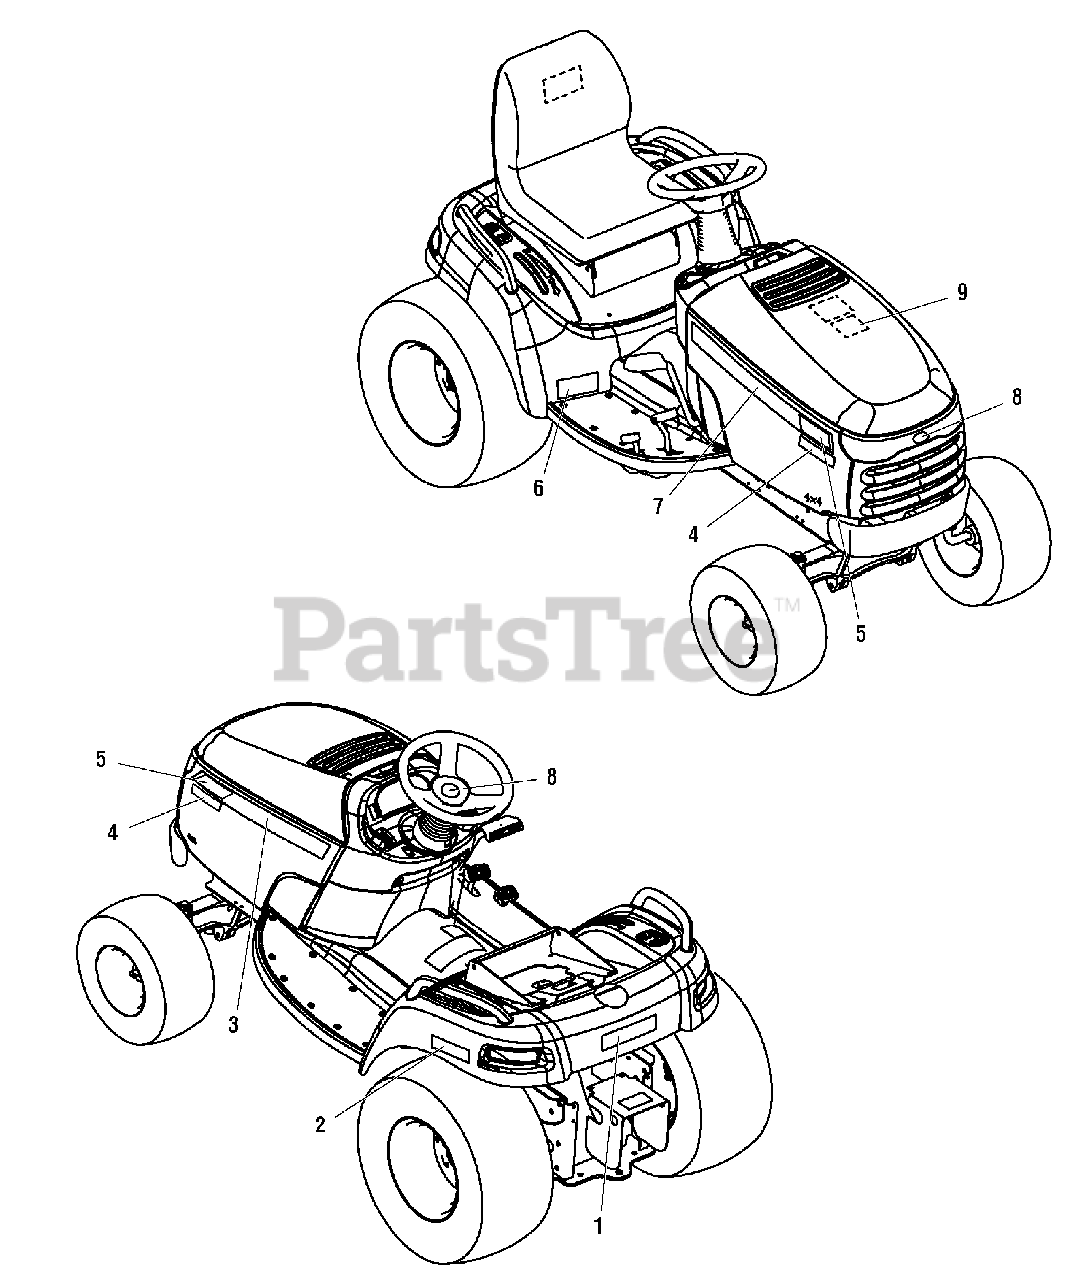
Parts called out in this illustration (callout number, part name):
1	DECAL, Simplicity
1	DECAL, AGCO
1	DECAL, Massey Ferguson
2	DECAL, Automatic Traction Control, Orange
2	DECAL, Automatic Traction Control, Red
3	DECAL, Hood Stripe, LH, Simplicity
3	DECAL, Hood Stripe, LH, (Massey Ferguson)
3	DECAL, Hood Stripe, LH, (AGCO)
4	DECAL, 27HP LC, Black, (Massey Ferguson)
4	DECAL, 27HP LC, White, (AGCO)
4	DECAL, 27HP V-Twin, Black, (Massey Ferguson)
4	DECAL, 27HP V-Twin, Black, (AGCO)
5	DECAL, 2927, (Massey Ferguson)
5	DECAL, 2027, (AGCO)
6	DECAL, Legacy XL, 27 HP
7	DECAL, Hood Stripe, RH, Simplicity
7	DECAL, Hood Stripe, RH (Massey Ferguson)
7	DECAL, Hood Stripe, RH (AGCO)
8	DECAL, Simplicity Icon
9	DECAL, Touch Up, Orange
9	DECAL, Touch Up, Red
